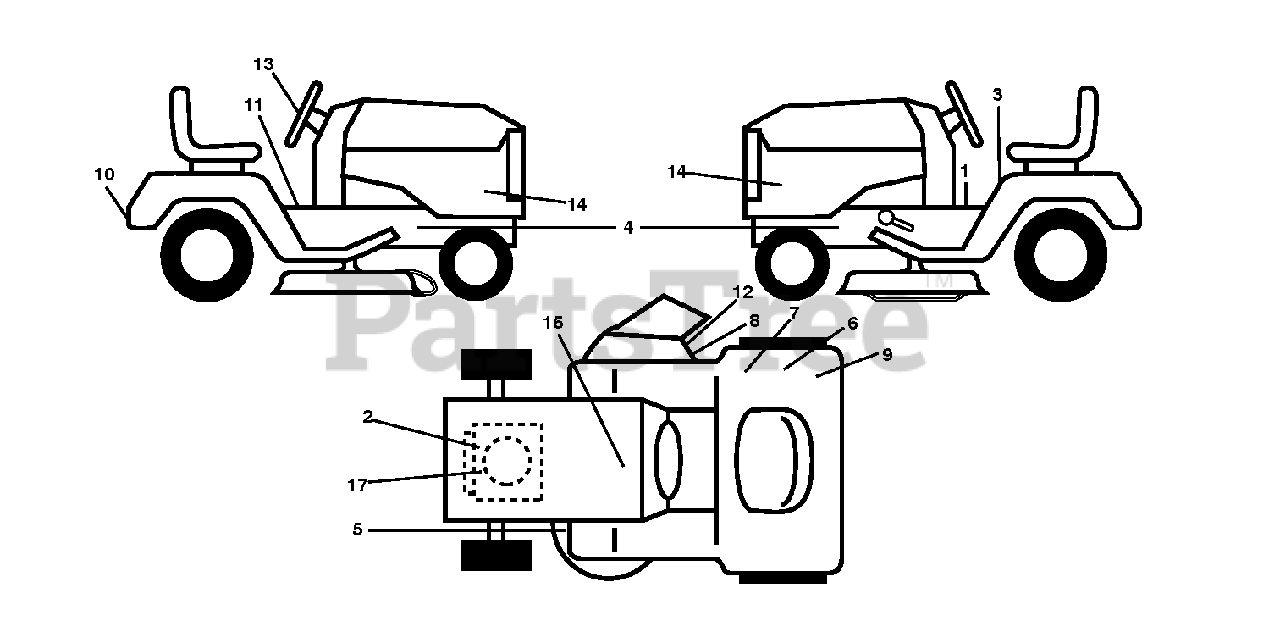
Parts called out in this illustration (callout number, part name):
1	DECAL PARK BRAKE
5	DECAL V BELT SCHEMATIC
7	DECAL.80 DBA.AUSTRALIA
8	DECAL, DEFLECT WARNING
12	DECAL.INTERNATIONL.CUTFINGER
15	DECAL BTRY SYMBOLS
